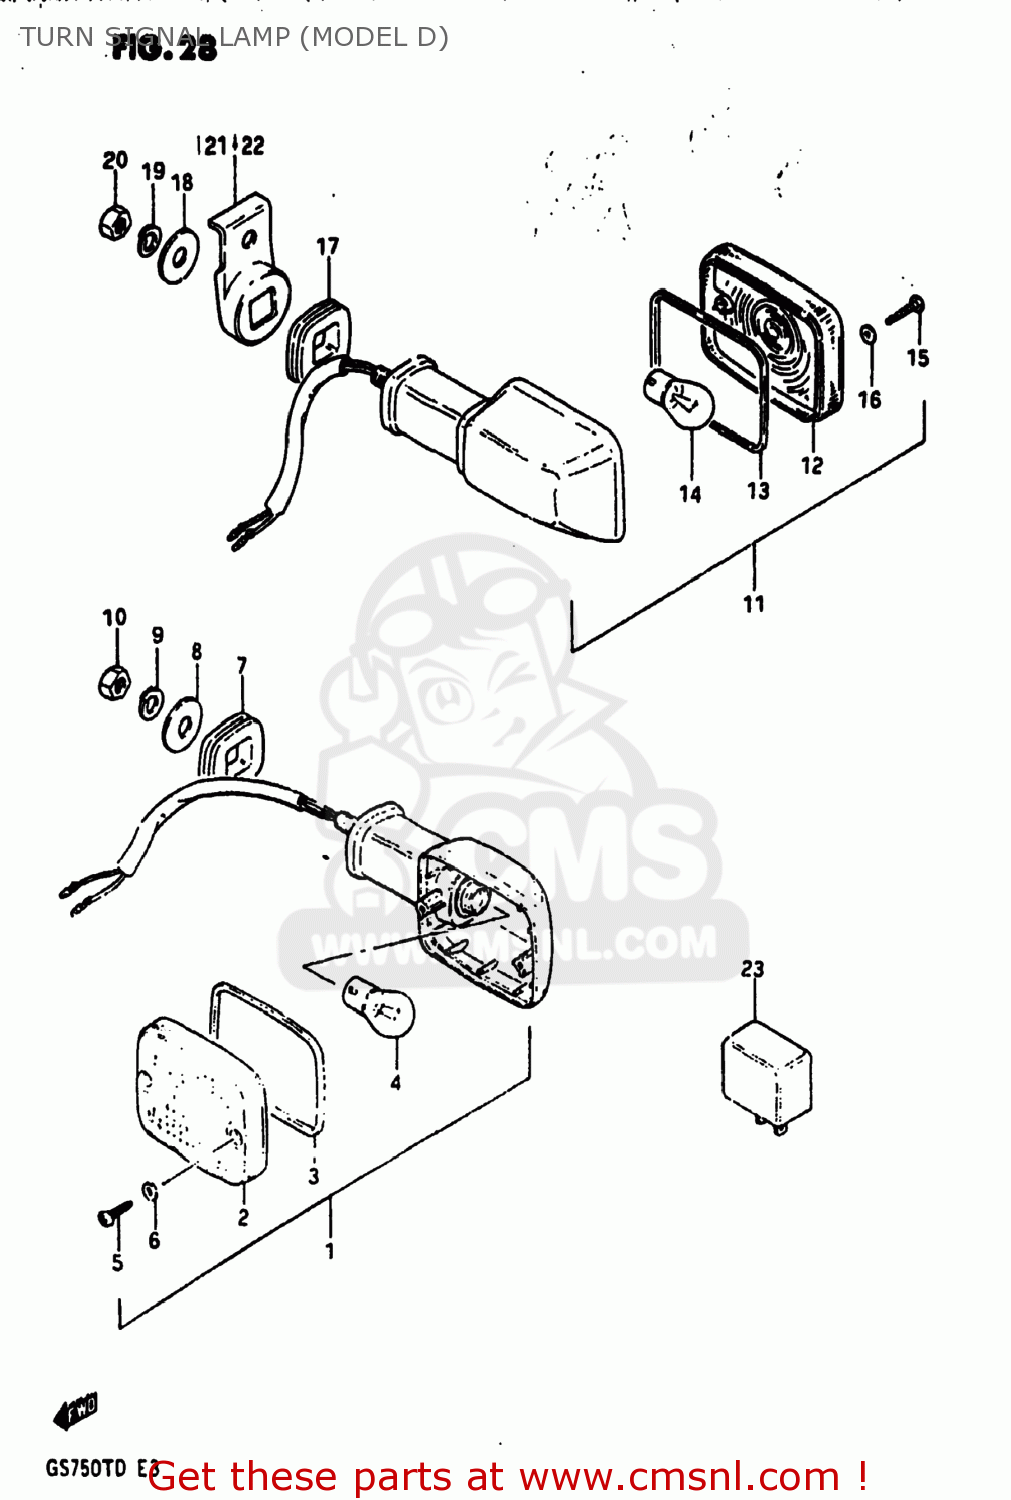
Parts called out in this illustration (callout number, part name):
1	LAMP ASSEMBLY,FRONT TURN SIGNAL
2	LENS
3	GASKET (NAS)
4	BULB(12V23W,STANLEY,A4577A)
5	SCREW
6	GASKET (NAS)
7	CUSHION
8	WASHER (10.5X30X2.3)
9	LOCK WASHER
10	NUT
11	LAMP ASSEMBLY,REAR TURN SIGNAL
12	LENS
13	GASKET (NAS)
14	BULB(12V23W,STANLEY,A4577A)
15	SCREW
16	GASKET (NAS)
17	CUSHION
18	WASHER (10.5X30X2.3)
19	LOCK WASHER
20	NUT
21	BRACKET,REAR TURN SIGNAL
22	BRACKET,REAR TURN SIGNAL
23	RELAY,TURN SIGNAL
